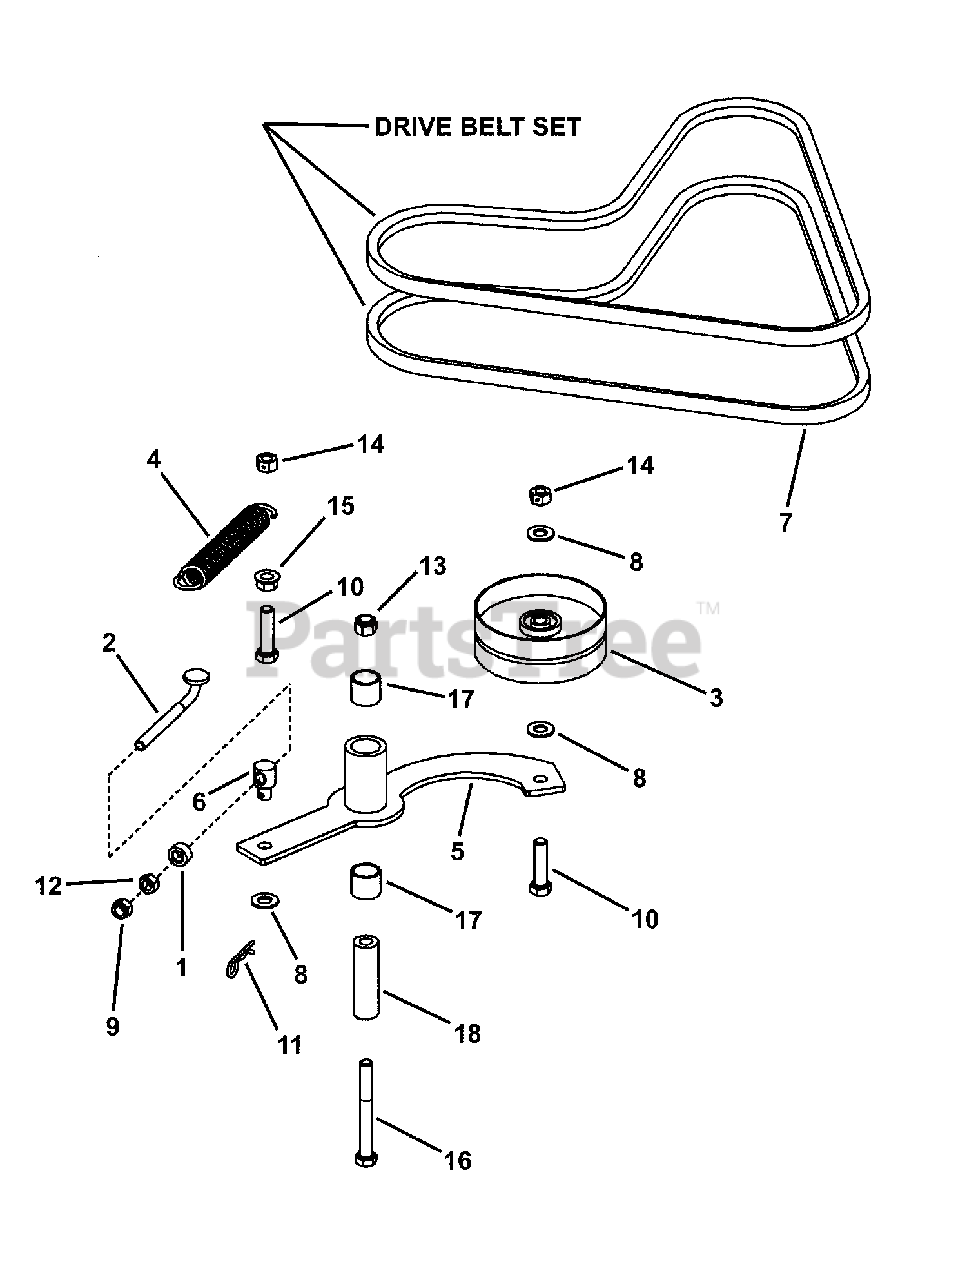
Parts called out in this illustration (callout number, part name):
1	SPACER, .340 I.D. x .63 O.D. x .310 Thick
2	ADJUSTER, Chain (5/16-18 thread)
3	IDLER, 4" OD x .391 ID x 1.25 Backside
4	SPRING, Extension
5	WELDMENT, Idler Arm
6	SWIVEL, Adjustable
7	BELT, Hydro Drive (HA Section, 47.5 Effective Length)
8	WASHER, 3/8" SAE Flat
9	NUT, 5/16-18 HEX NYLON LOCK
10	SCREW, 3/8-16 x 1-1/2 Hex Head Cap GR 5
11	HAIR PIN, 3/32 x 1-1/2"
12	NUT, 5/16-18 Hex, GR 5 or B
13	NUT, 3/8-24 Hex Nyloc
14	NUT, 3/8-16 Hex Center Lock
15	NUT, 3/8-16 HEX SERRATED FLANGE
16	SCREW, 3/8-16 x 3-1/4" Hex Head Cap, GR 5
17	BUSHING, SLEEVE, 3/4 ID, GV3031224
18	BOSS, IDLER,YELLOW GV3036304
